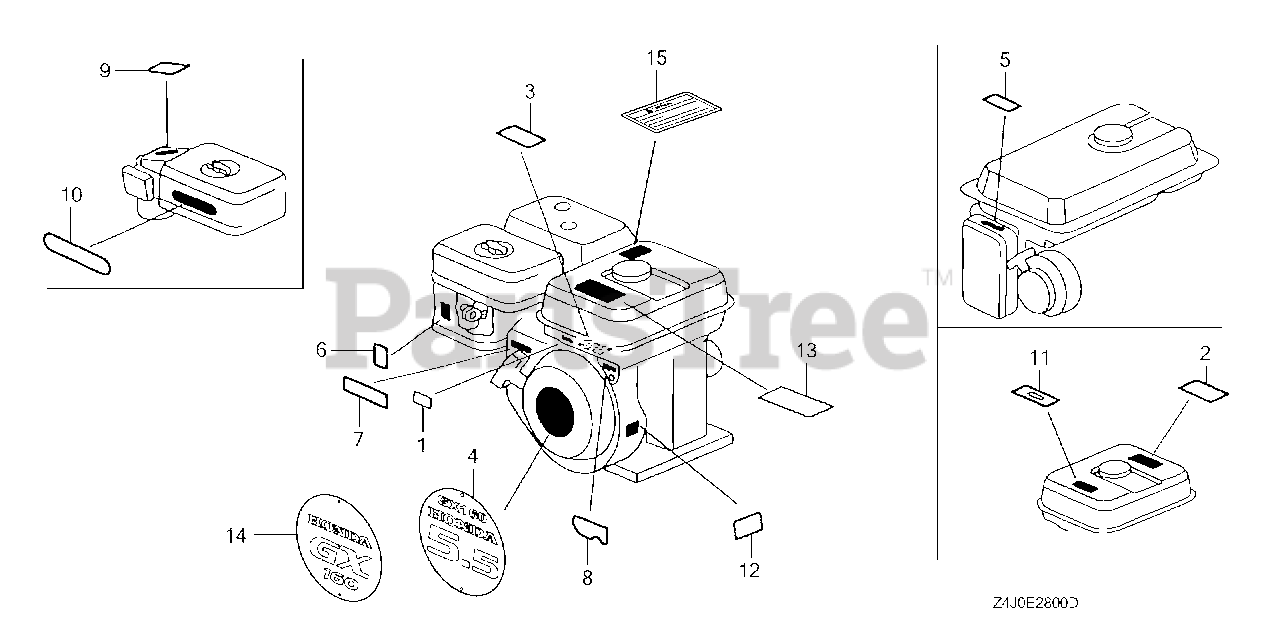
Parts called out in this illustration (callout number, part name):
3	MARK, OPERATOR CAUTION (ENGLISH)(MADE IN JAPAN)
3	MARK, OPERATOR CAUTION (PICTOGRAPH)(MADE IN JAPAN)
4	EMBLEM (GX160)
6	MARK, CHOKE
8	MARK, ENGINE SWITCH
14	EMBLEM (GX160)
